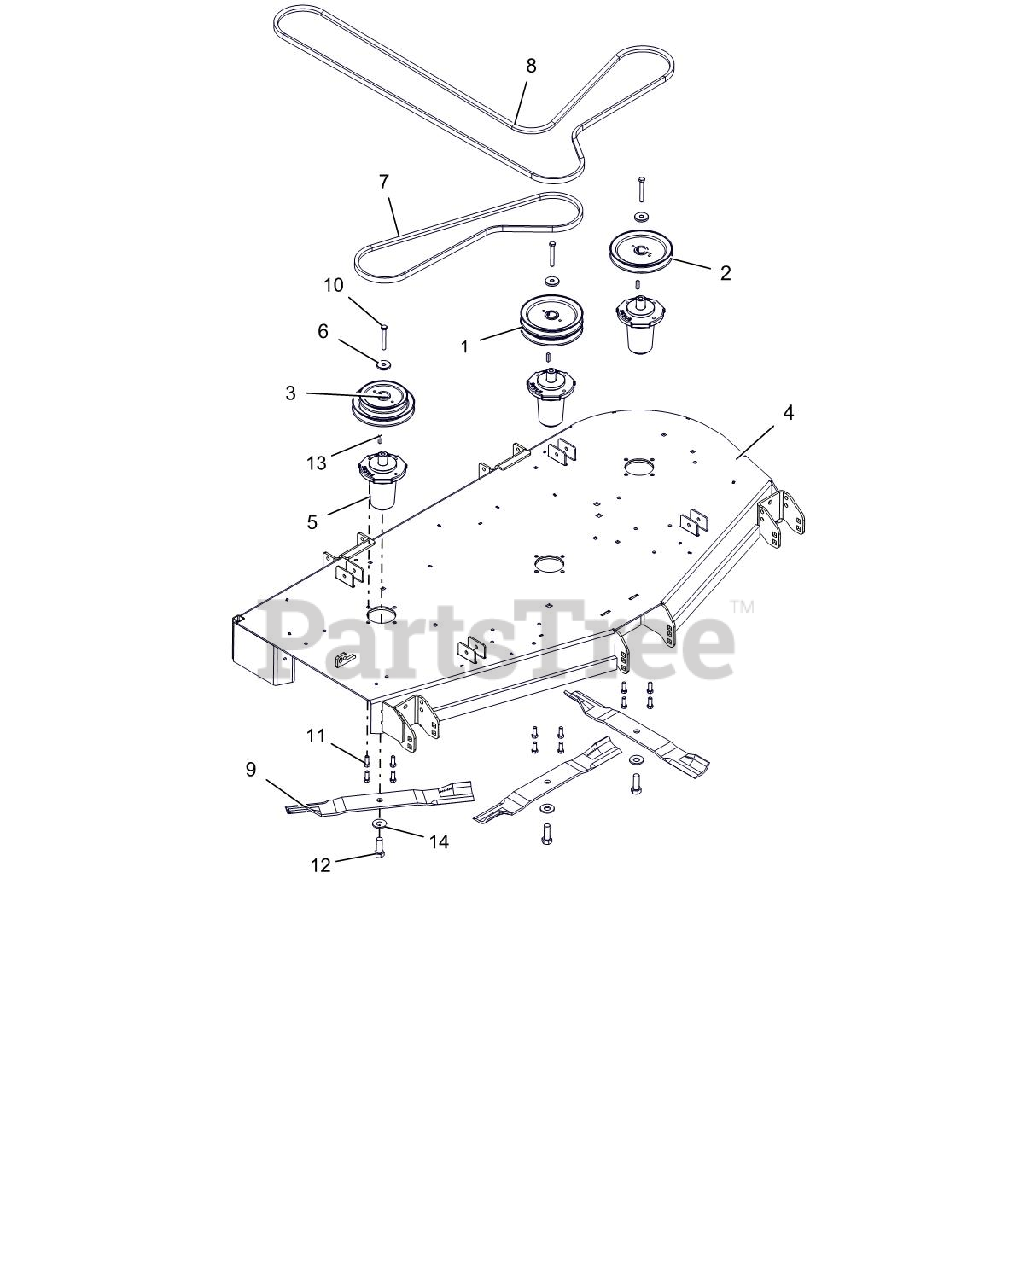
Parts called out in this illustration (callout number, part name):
1	PULLEY, DOUBLE-1"ID X 6.75"OD
2	PULLEY, V-1" ID X 6.75" OD
3	PULLEY, DBL-1"IDX6.75"&5.25"OD
4	60"SIDE DISCH DECK WMT W/SAFE
5	ASM, MAINT FREE SPINDLE
6	RETAINER, SHEAVE
7	V-BELT, B-COGGED
8	V-BELT, HB-WRAPPED
9	BLADE, MOWER (20.50")
10	BLT-HEX .38-16X2.75 GR8 YWZC
11	BLT-HEX .38-16X1.0 GR8 YZ EP30
12	BLT-HEX .62-18X1.75 GR8 YWZC
13	KEY, SQ .25X.25X1.00 RC 40-50
14	WSHR-BLVL .669X1.535X.138
